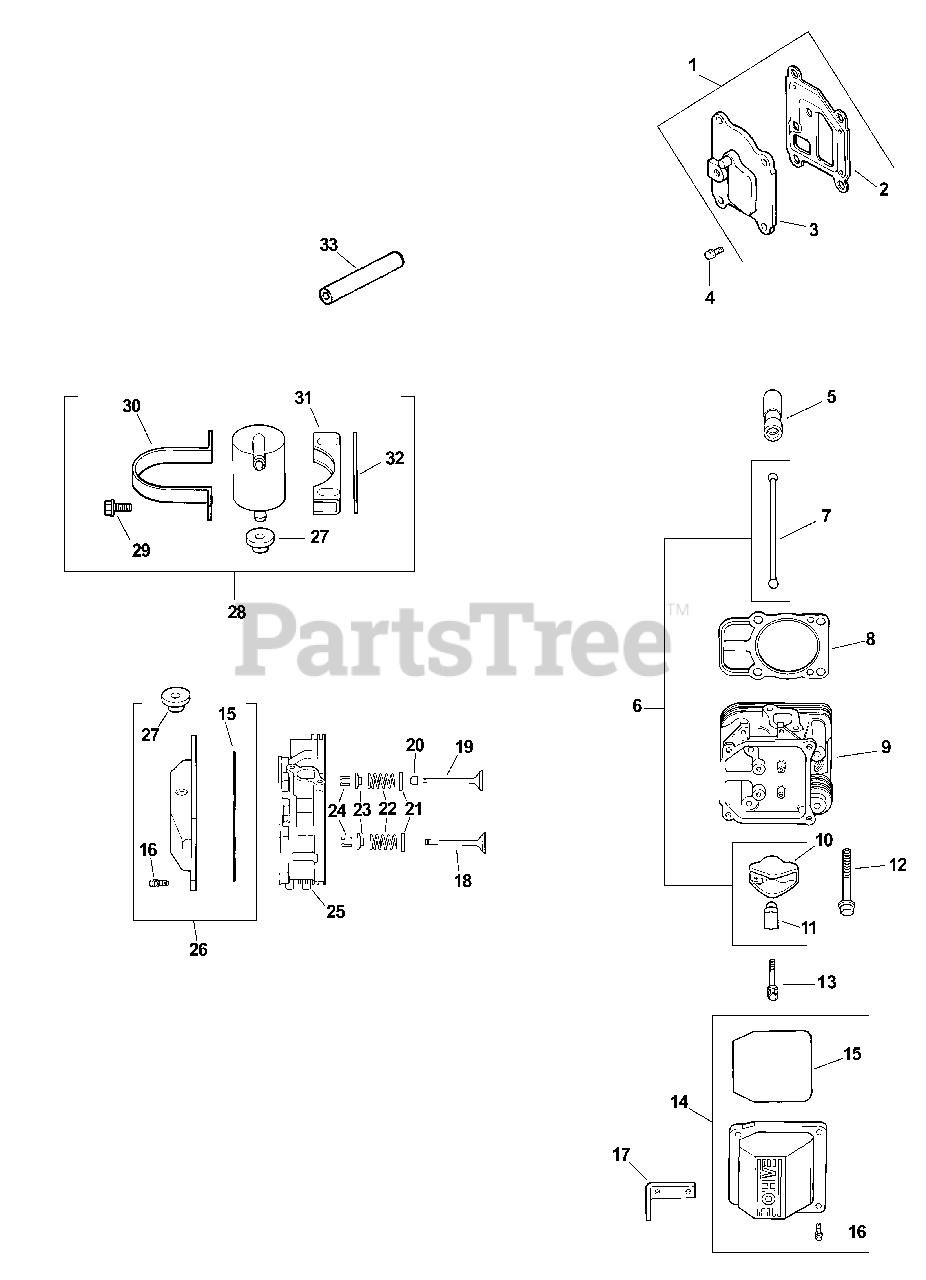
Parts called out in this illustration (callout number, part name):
1	KIT, BREATHER COVER W/GASKET
2	GASKET, BREATHER-USE 24 041 67-S
3	COVER, BREATHER -USE 24 096 125-S
4	SCREW,FLG THD FRM M6X1.0X20-(#25086396S)
5	LIFTER, HYDRAULIC VALVE-USE 25 351 10-S
6	KIT, VALVE TRAIN
7	ROD, PUSH
8	KIT, CYL HEAD GASKET (C17-22)
9	HEAD, ASSEM CYLINDER #2 -USE 24 318 113-
10	ARM, ROCKER
11	PIVOT, CYLINDRICAL ROCKER ARM-USE 24 599
12	SCREW - USE 62 086 08-S
13	SCREW, ROCKER ARM PIVOT-USE M-640034-S
14	KIT, VALVE COVER-PLAIN
15	O-RING (YELLOW) -USE 24 153 30-S
16	SCREW, FLG M6X1.0X30
17	STRAP, LIFTING-USE 25 445 03-S
18	VALVE, EXHAUST (STD) - USE 32 016 01-S
19	VALVE, INTAKE (STD)
20	SEAL, VALVE STEM - (#2503214S)
21	RETAINER, SPRING
22	SPRING, VALVE
23	RETAINER, VALVE SPRING - USE 25 173 28-S
24	KIT, RETAINER
25	HEAD, ASSEM CYLINDER #1 -USE 24 318 105-
26	KIT, VALVE COVER
27	GROMMET, RUBBER
28	KIT, BREATHR SEPARATR-(#24755241S)
29	SCREW,FLG THD FRM M5X0.8X16-(#25086398S)
30	STRAP, BREATHER - USE 24 755 241-S
31	BRACKET, BREATHER SEPARATOR
32	SPACER
33	HOSE, BREATHER-USE 24 326 63-S
2401602-S	VALVE, EXHAUST (.25)
2401702-S	VALVE, INTAKE (.25)
